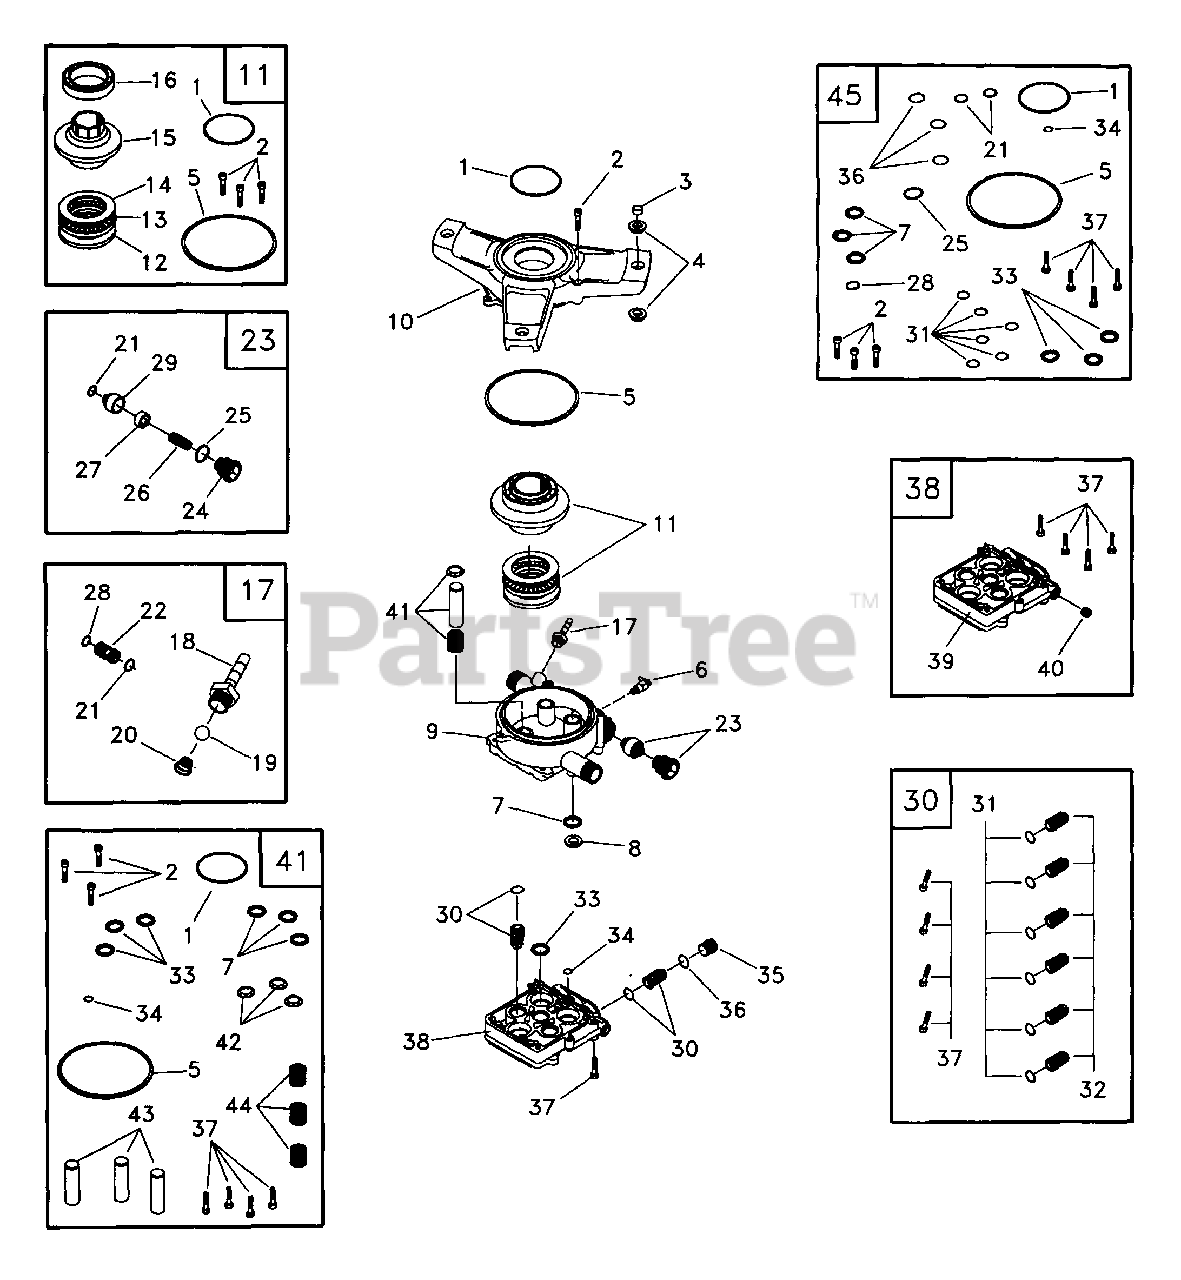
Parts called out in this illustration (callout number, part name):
1	SEAL, Engine Donut
2	SHCS, M6 - 1 x 25
3	SLEEVE, Grommet Spacer
4	BUSHING, Rubber Mount
5	O-RING, Housing Seal
6	THERMAL RELIEF, GPW-EG
7	SEAL, Oil Piston 15 TC4
8	SPACER, Pilot
9	HOUSING, Piston
10	ADAPTER, Engine
11	KIT, AXIAL CAM SERV
12	WASHER, Brg. 36 x 65 x 6 Thk
13	ASSY, Brg. Cage 45 x 65
14	WASHER, Brg. 45 x 65 x 1
15	CAM, Axial 5.6 VS
16	BALL BEARING, 35 x 72 x 17
17	KIT, CHEM INJECT
18	FITTING, Chem Inject
19	BALL, Chem Inject
20	SPRING, Chem Inject
21	O-RING, Venturi & Seat, Black
22	VENTURI, Chem Inject
23	KIT, UNLOADER
24	CAP, Unloader
25	O-RING, Unloader Cap
26	SPRING, Unloader
27	PISTON ASSY, Unloader
28	O-RING, Venturi, Yellow
29	SEAT, Unloader
30	KIT, CHECK VALVES
31	O-RING, Check Valve
32	ASSY, Check Valve
33	SEAL, Double-Lip
34	O-RING, Hi-Pressure Transfer
34	O-RING, High Pressure Transfer
35	CAP, Outlet Check Valve
36	O-RING, Outlet CV Cap
37	SHCS, M6-1.0 x 35
38	KIT, HEAD CASTING SFG
39	HEAD, Pump
40	PLUG, 1/8-28 W/VIRB
41	KIT, PISTON & SPRING
42	RETAINER, Piston Spring
43	PISTON, Dia. 15 x 65
44	SPRING, Piston Return
45	KIT, O-RING/SEAL SERV
